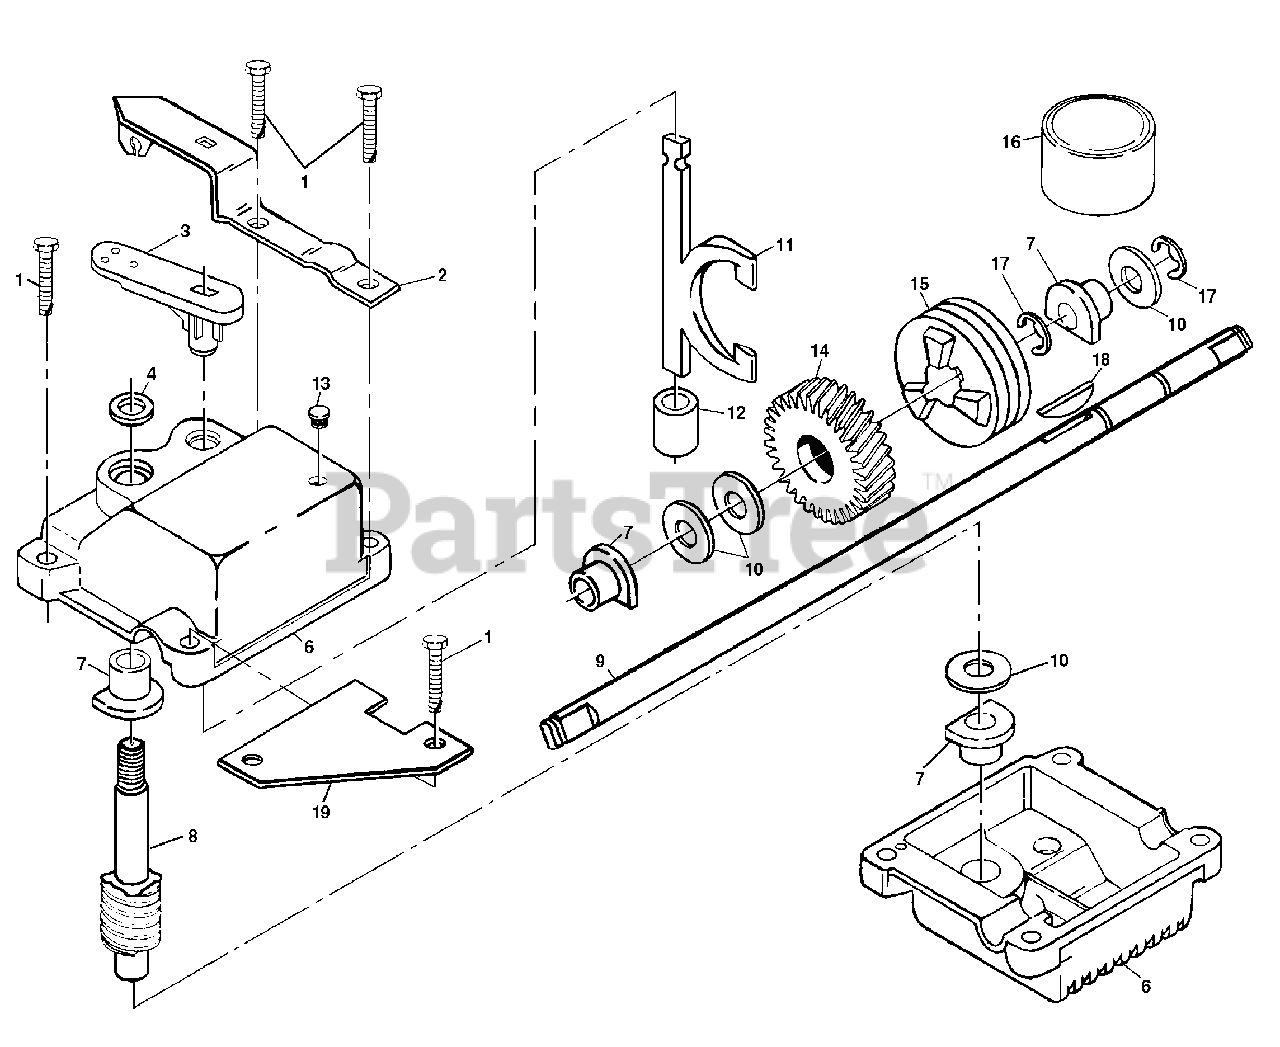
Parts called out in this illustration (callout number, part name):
1	Tapping Screw 1/4-20 x 1-1/4
2	Engagement Bracket
5	Grooved Pin 1/8 x 5/8
6	Gear Case Halves Kit
8	Worm Shaft
9	Drive Shaft
10	Hardened Washer
11	Clutch Yoke
14	Helical Gear
15	Clutch Jaw
16	Grease
18	Hi-Pro Key
19	Spring Bracket
